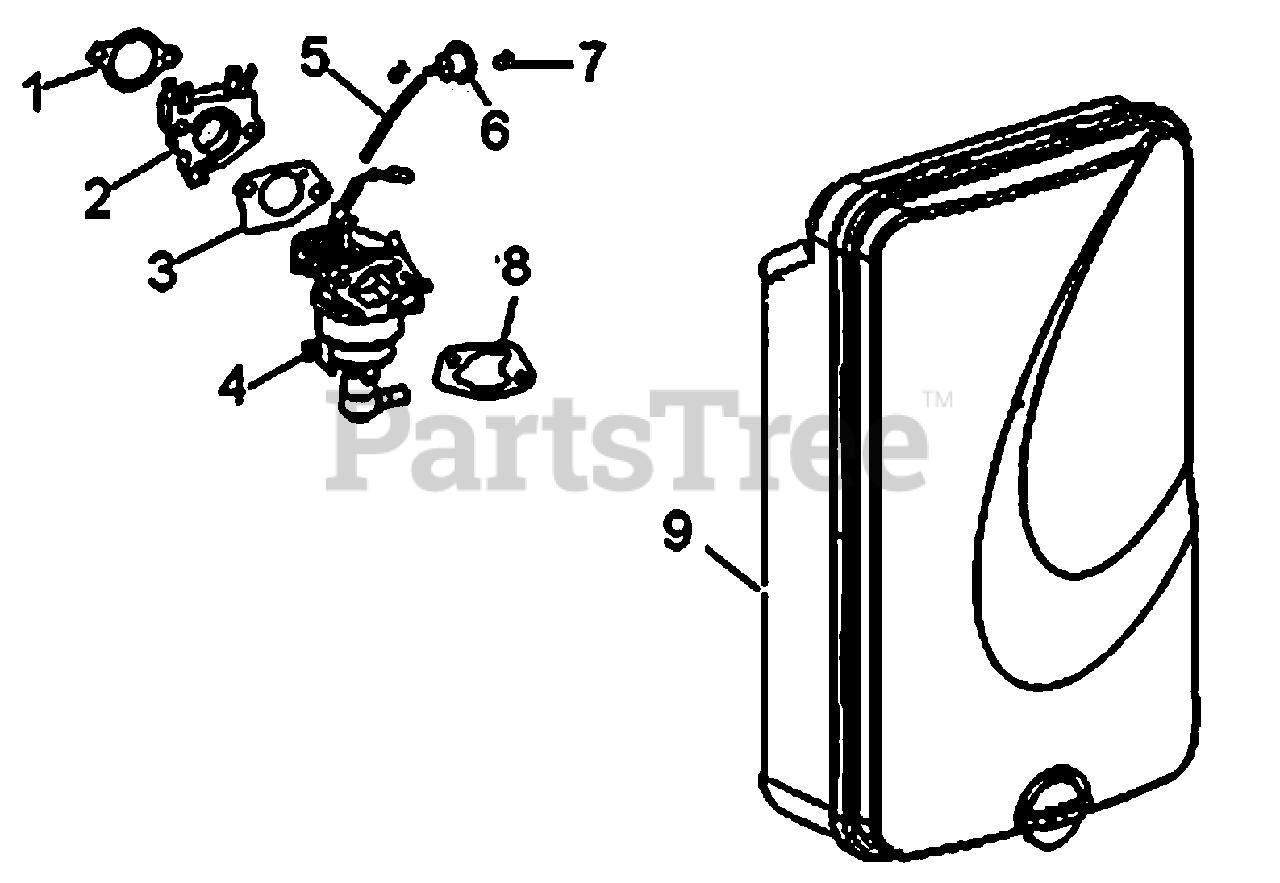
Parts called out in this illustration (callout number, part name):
1	GASKET, INSULATOR
2	SPACER, CARBURETOR
3	GASKET, CARB. TO SPACER
4	CARBURETOR ASSY
5	HOSE, FUEL
6	FILTER, FUEL (IN-LINE)
7	CLAMP, HOSE
8	GASKET, CARB. TO AIR CLEANER
9	AIR CLEANER
